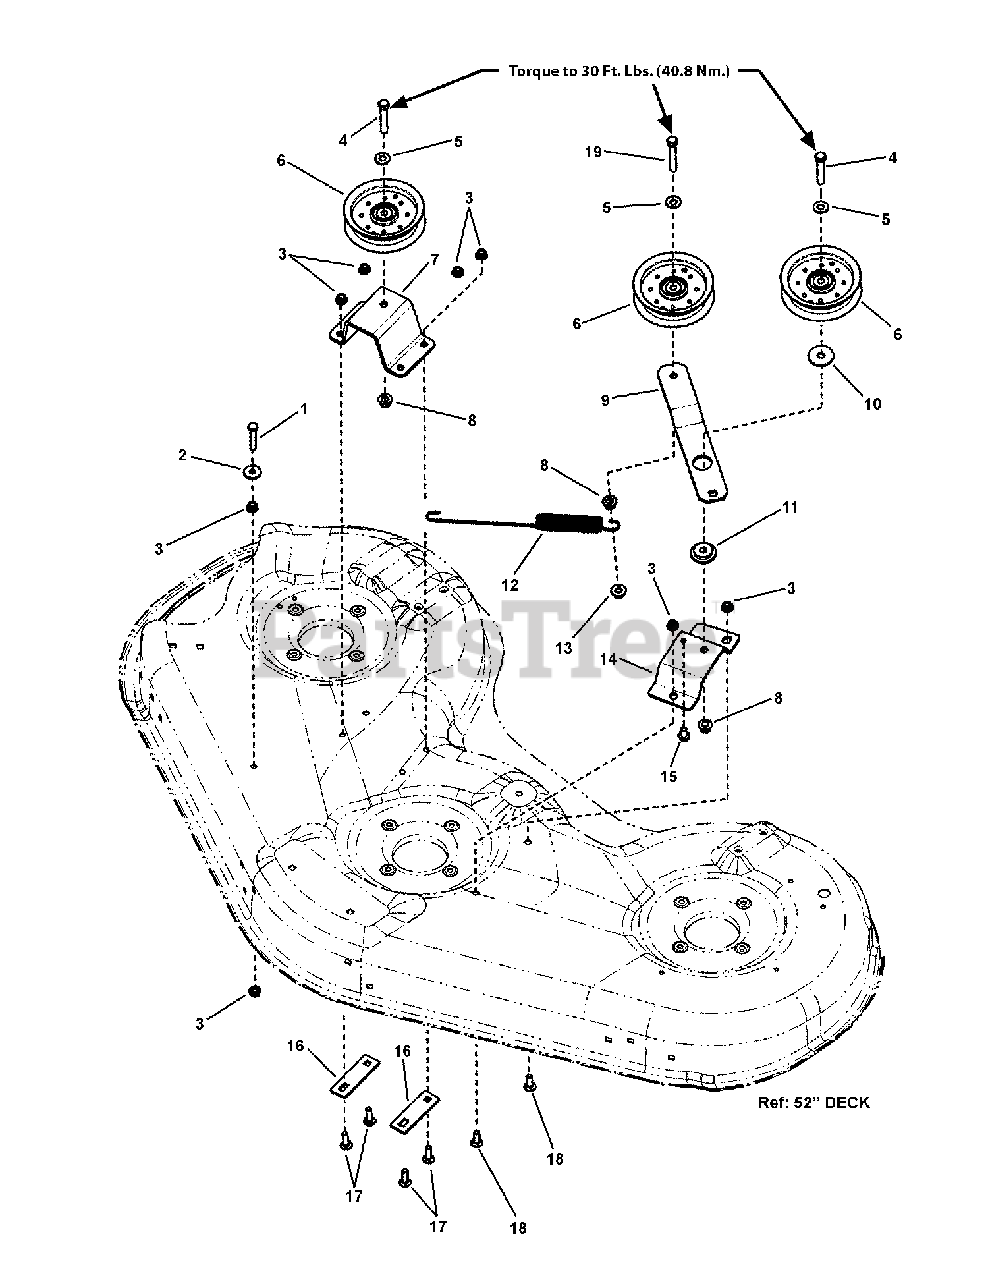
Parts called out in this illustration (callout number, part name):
1	SCREW, 5/16-18 X 1-3/4"Hex Head Cap, GR 5 Yellow Zinc
2	WASHER, 5/16" Flat (.341 ID x 1.00 OD x .13 Thick) Black
3	NUT, 5/16-18 Hex Flange Lock, Large, Black
4	SCREW, 3/8-16 x 2-1/2" Hex Head Cap, GR 5 Black
5	WASHER, 3/8" Flat (.41 ID x .87 OD)
6	PULLEY, Idler 46/52, Mowers
7	BRACKET, Idler, Rear, 46/52 RZT
8	NUT, 3/8-16 Hex Flange lock, GR F, BZ
9	ARM, Idler, 46/52 RZT
10	WASHER, .406 x 1.50 x .120 Flat, Yellow Zinc
11	SPACER, .406 ID x 1.50 OD x .350 Thick, PM
12	SPRING, Extension, PTO
13	NUT, 3/8-16 Hex Flange Lock, Large, Black
14	BRACKET, Idler Mount Front 46/52, Black
15	SCREW, 5/16-18 x 3/4" Hex Washer Head Self-Tap, Black
16	PLATE, Idler Bracket 46/52 Mowers
17	BOLT, 5/16-18 x 1" Round Head Short Square Neck, GR 5 Zinc
18	BOLT, 5/16-18 x 7/8" Round Head Short Square Neck, GR 5, Black
19	SCREW, 3/8-16 x 2-1/2" Hex Head Cap GR 5 Black
